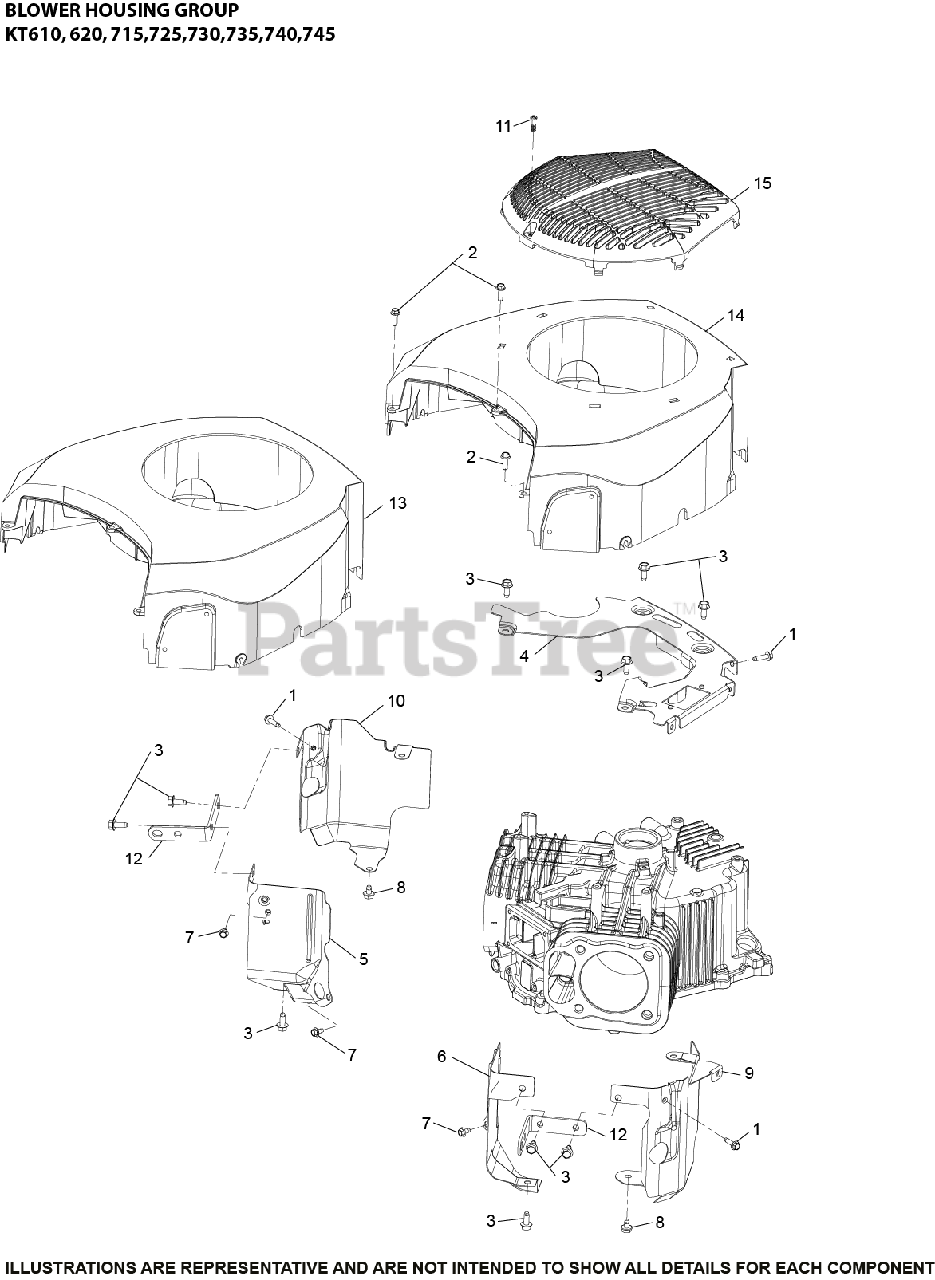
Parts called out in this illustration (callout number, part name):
1	SCREW, THREAD FORMING - USE 25 086 473-S
2	SCREW, HI-LOW
3	SCREW, THREAD FORMING
4	PLATE, BACKING
5	BAFFLE, VALLEY #1
6	BAFFLE, VALLEY #2
7	SCREW, THREAD FORMING
9	BAFFLE, LEFT BARREL
10	BAFFLE, RIGHT BARREL
11	SCREW, M5-2.42 (PT) THREAD
14	KIT, BLOWER HOUSING
15	GUARD, FIXED
